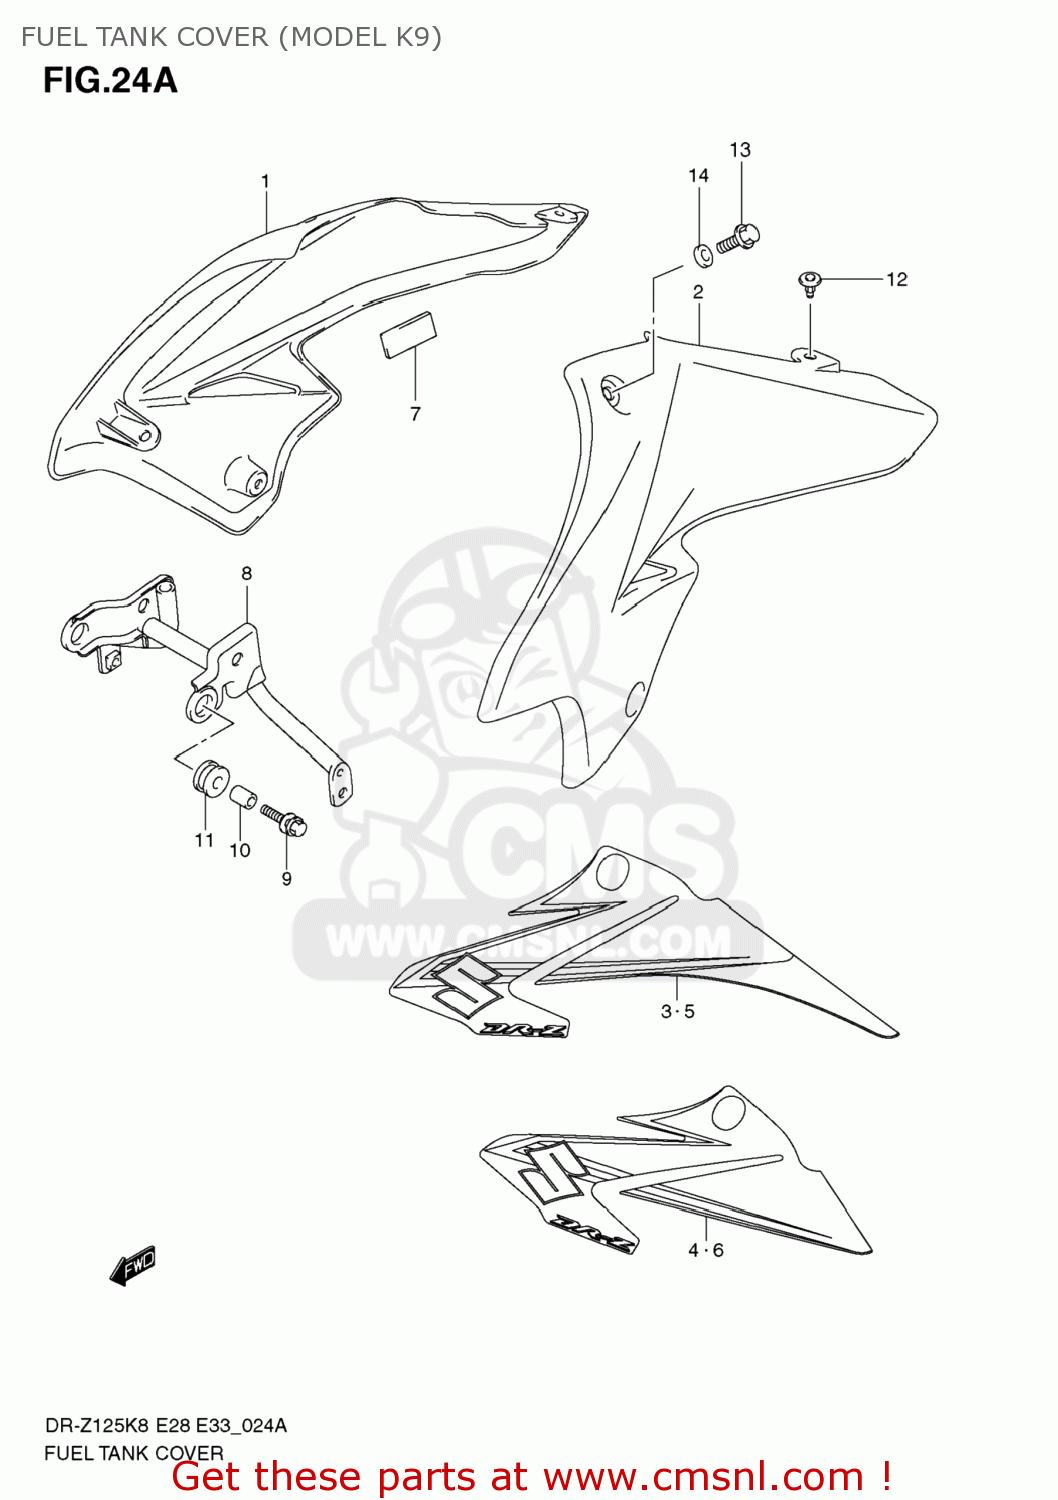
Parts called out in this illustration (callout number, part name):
1	COVER,FUEL TANK,R
2	COVER,FUEL TANK,L
3	TAPE,FUEL TANK COVER,R
4	TAPE,FUEL TANK COVER,R
5	TAPE,FUEL TANK COVER,L
6	TAPE,FUEL TANK COVER,L
7	CUSHION,FUEL TANK COVER
8	BRACKET,FUEL TANK FR
9	BOLT(6X25)
10	SPACER(6.5X9X13.5)
11	CUSHION,FUEL TANK SIDE
12	CLIP(BLACK)
13	BOLT
14	WASHER
